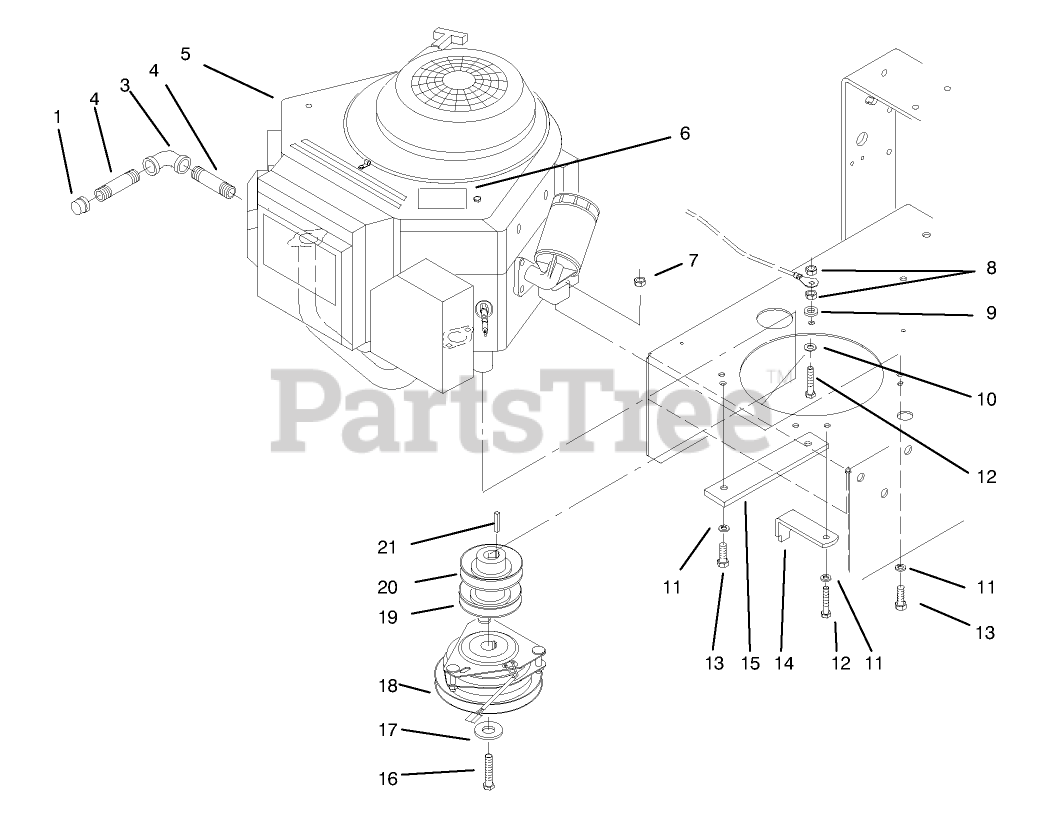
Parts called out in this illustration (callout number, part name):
1	CAP-PIPE
3	ELBOW-90 DEG
4	NIPPLE-PIPE
6	DECAL-SURFACE, HOT
7	NUT-LOCK, NI
8	NUT-HEX
9	WASHER-LOCK
10	WASHER-PLAIN
11	WASHER-LOCK
12	SCREW-HH
13	SCREW-HH
14	Retainer-Clutch
15	Guard-Engine
16	SCREW-HH
17	WASHER
18	CLUTCH/BRAKE
19	SHEAVE-LOWER HALF
20	SHEAVE-UPPER HALF
21	KEY-SQUARE
